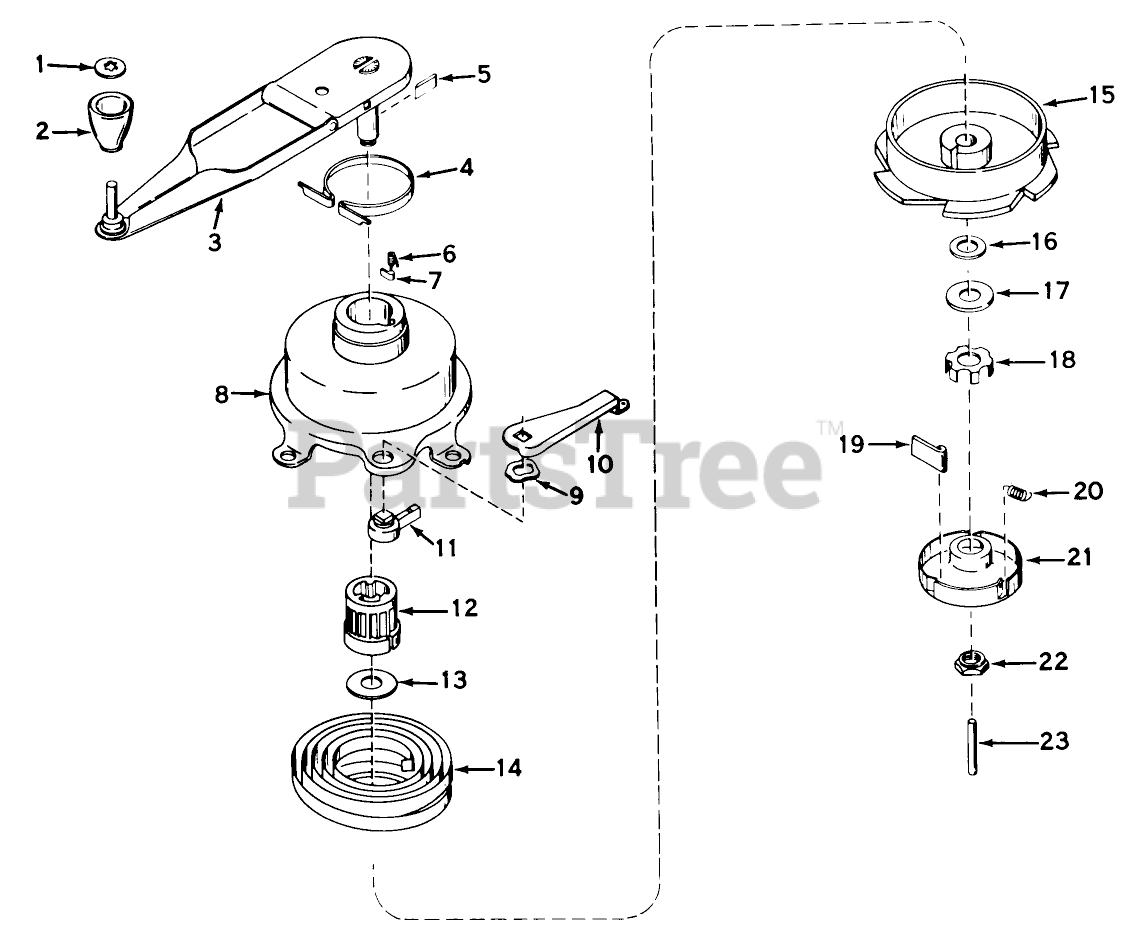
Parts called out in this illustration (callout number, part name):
1	Fastener, Handle
2	Knob, Starter handle
3	Handle Assy., Starter Incl. Nos. 4 5)
4	Band, Brake
5	Dog, Wind
6	Spring, Lock Dog
7	Dog, Lock
8	Housing Release Assy., Off set (Incl. Nos. 9, 10 11)
9	Washer, Wave
10	Release Lever, Offset
11	Release Assy.
12	Bearing, Center
13	Washer, Spacer
14	Spring, Power
15	Hub, Spring
16	Washer, Shim (Use as req-d)
17	Washer, Brake
18	Brake
19	Dog-Starter
20	Spring, Retainer
21	Retainer
22	Nut, Shoulder
23	Pin, Centering
